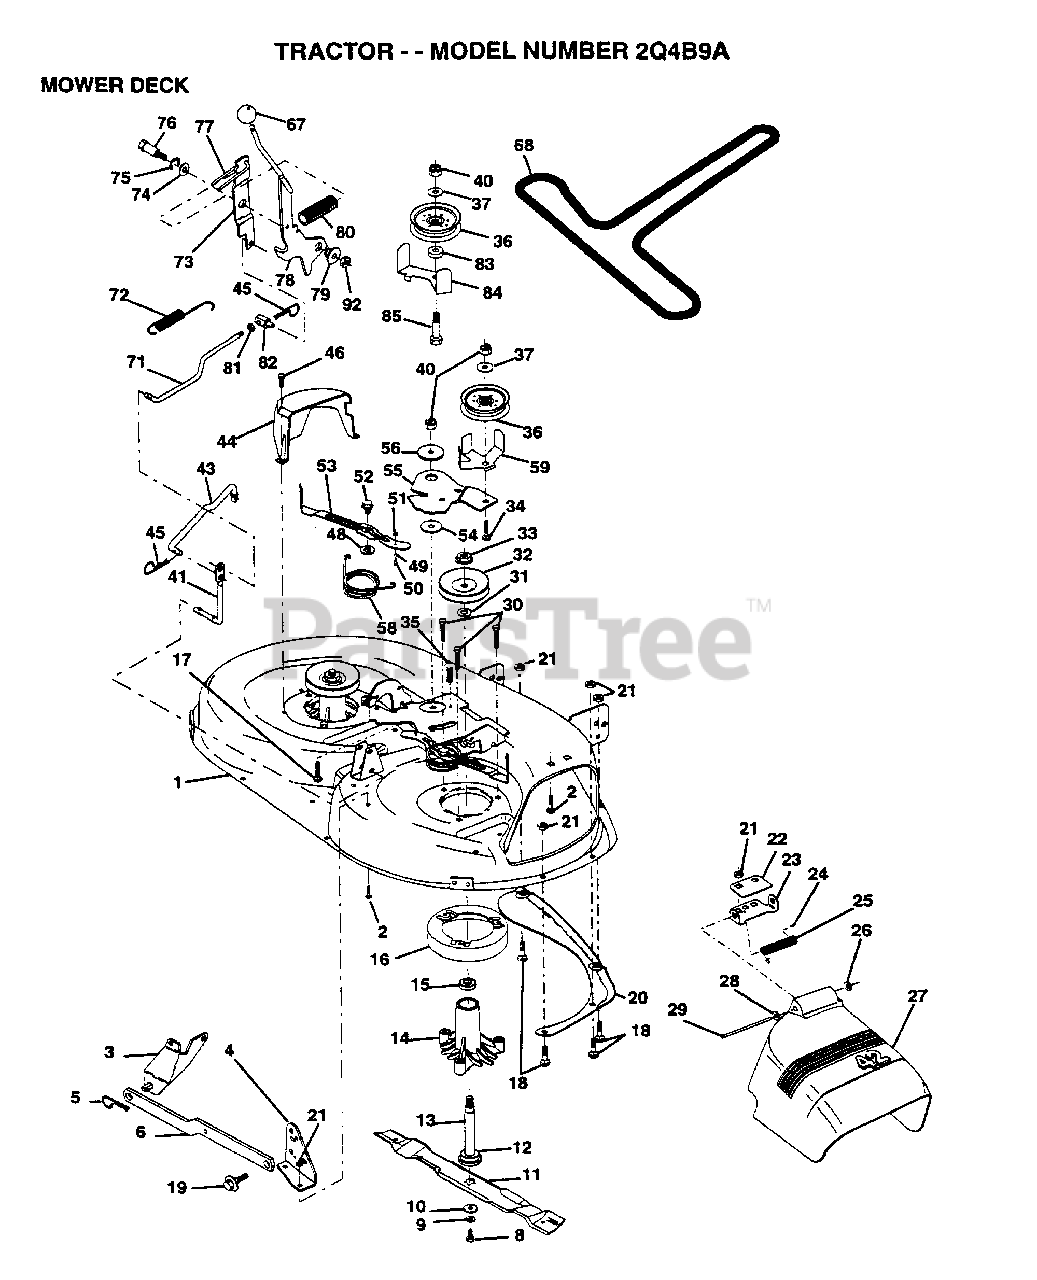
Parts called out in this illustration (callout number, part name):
1	DECK.WELD.42.
2	BOLT
3	BRKT ASM SWAY BAR
4	BRKT DECK SW BAR
8	BLADE BOLT
10	WASHER.HARD.BLADE
11	"BLADE.42"" HIPERF"
12	BEARING.BALL
14	HSG ASM MANDREL
15	BEARING
16	STRIPPER RND MWR
17	BOLT RDHD 3/8-16
18	BOLT
19	BOLT SHD 5/16-18
22	STIFFENER BRKT
23	DEFLECTOR BRKT
24	CAP-SLEEVE LT
25	SPRING TORSION
26	NUT PUSH M
27	DEFLECTOR.SHIELD
28	WASHER
29	HINGE ROD
31	WASHER
34	BOLT
35	XMAS TREE FASTNER
36	FLAT IDLER PULLEY
37	WASHER
41	PIVOT ROD
43	ROD CLUTCH W/NIBS
44	GUARD MAND LH BLK
45	RETAINER M
46	SCREW.1/4-20X5/8
48	HARD SMALL WASHER
50	SHOULDER BOLT
51	LOCKNUT
52	BOLT.SHLD.5/16-18
53	BRAKE PAD ARM ASM
54	HARDENED WASHER
56	SPACER RETAINER
58	SPRING TORSN BRAK
59	GUARD IDLER TUV
67	KNOB T(3/8 HOLE)
68	BELT.V.T-PATH
71	ROD CLUTCH 38/42
72	RETURN SPRING
73	CLUTCH ARM SECOND
74	WASHER
75	RING
76	SHOULDER BOLT
77	SPRING KEEPER
79	BUSHING
81	NUT
82	TRUNION ADJ
83	WASHER
85	BOLT
92	NUT
